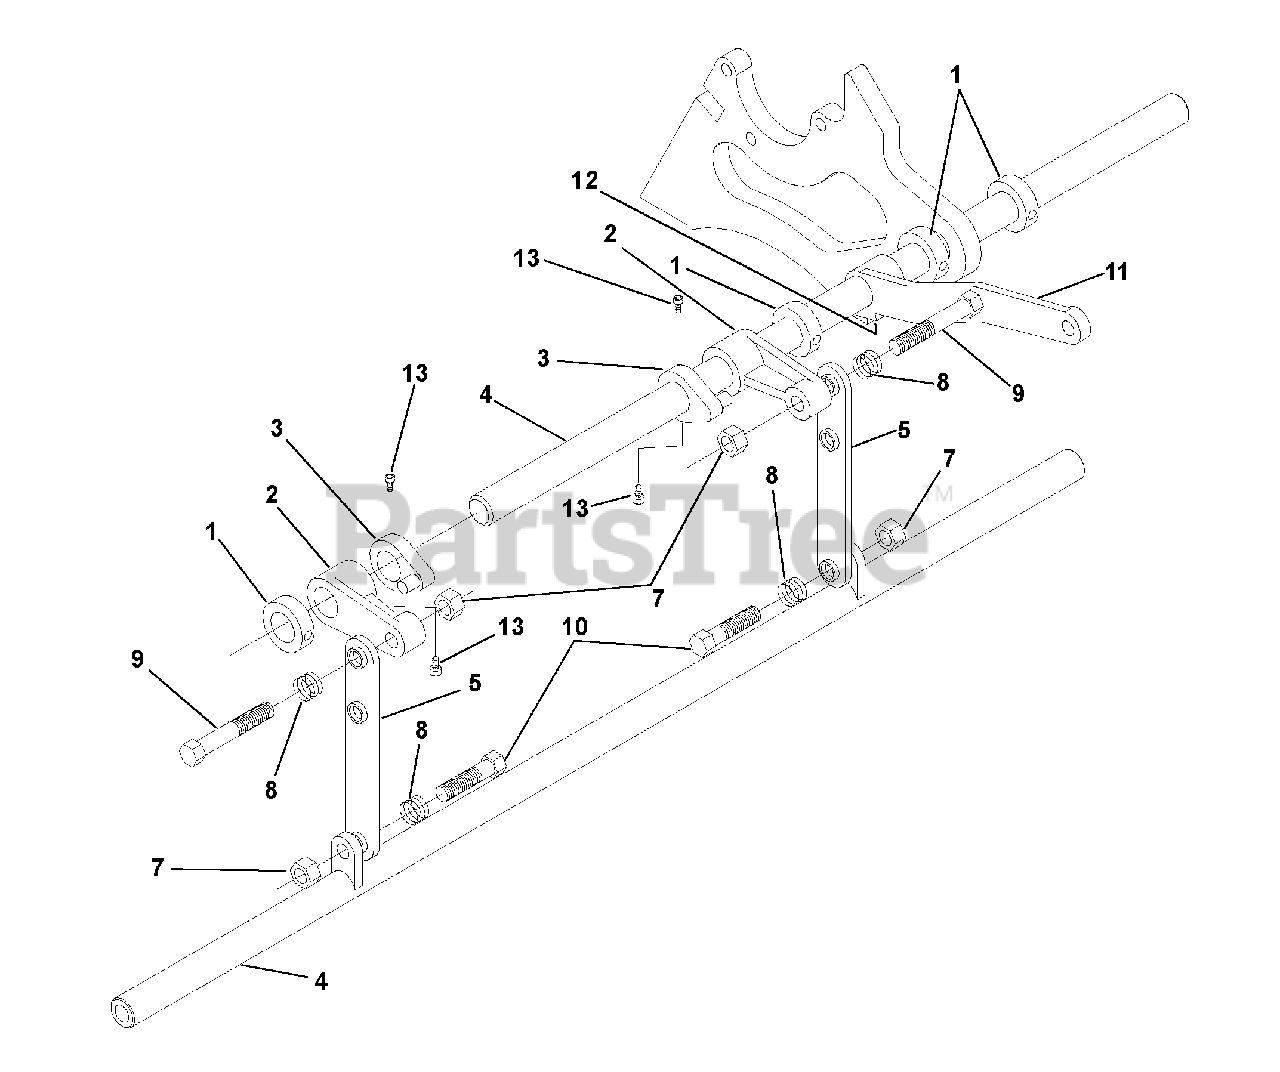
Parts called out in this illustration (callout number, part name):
2	Arm, Reel Lift
3	Collar, Lift
4	Shaft, Lift 30-Inch
5	Bar, Spacer 30-Inch
7	Nut, Hex .38-16
9	Cap Screw, Hex Head .38-16 x 1.75
10	Cap Screw, Hex Head .38-16 x 1.50
11	Lever, Reel Lift
12	Set Screw, Socket .312-24 x .25 Stainless Stee
13	Set Screw, Hex Socket Head .25 x .38 Grade 8
